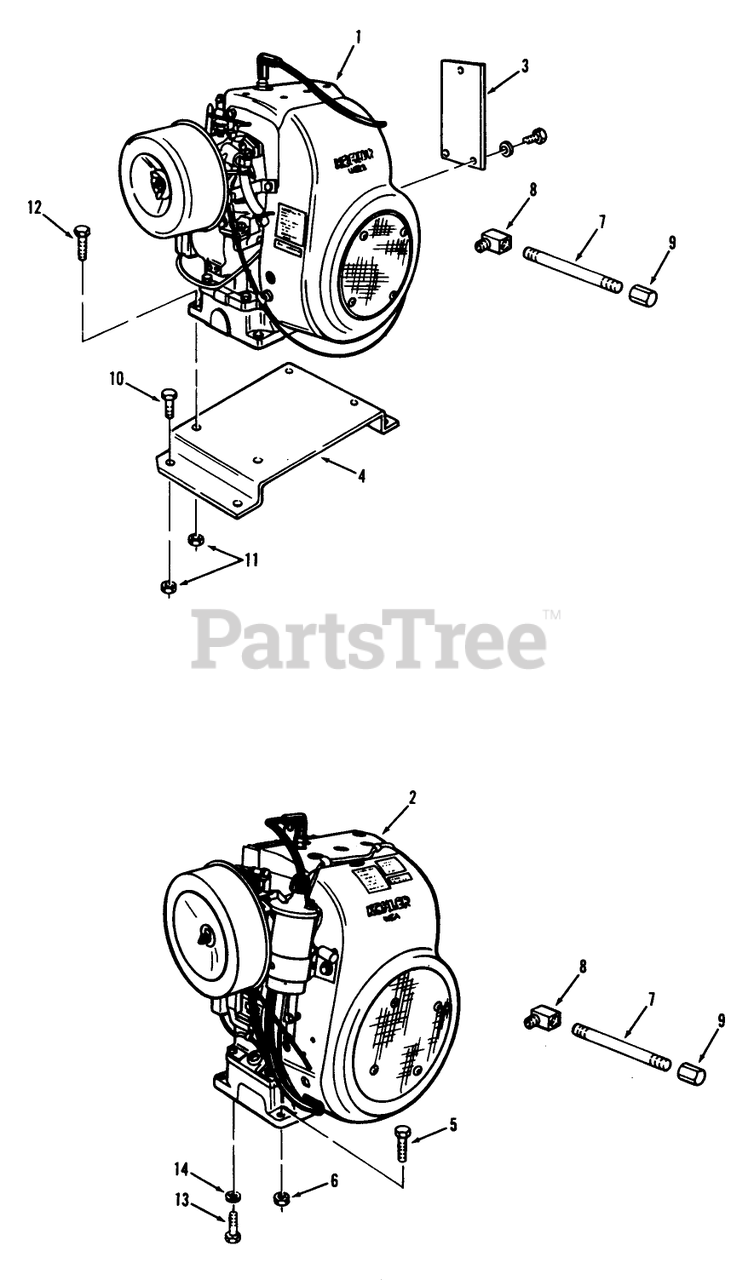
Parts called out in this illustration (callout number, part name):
1	Engine-8HP Kohler
1	Engine-7HP Kohler
2	Engine-12HP Kohler
2	Engine-1OHP Kohler
2	Engine-16HP Kohler
